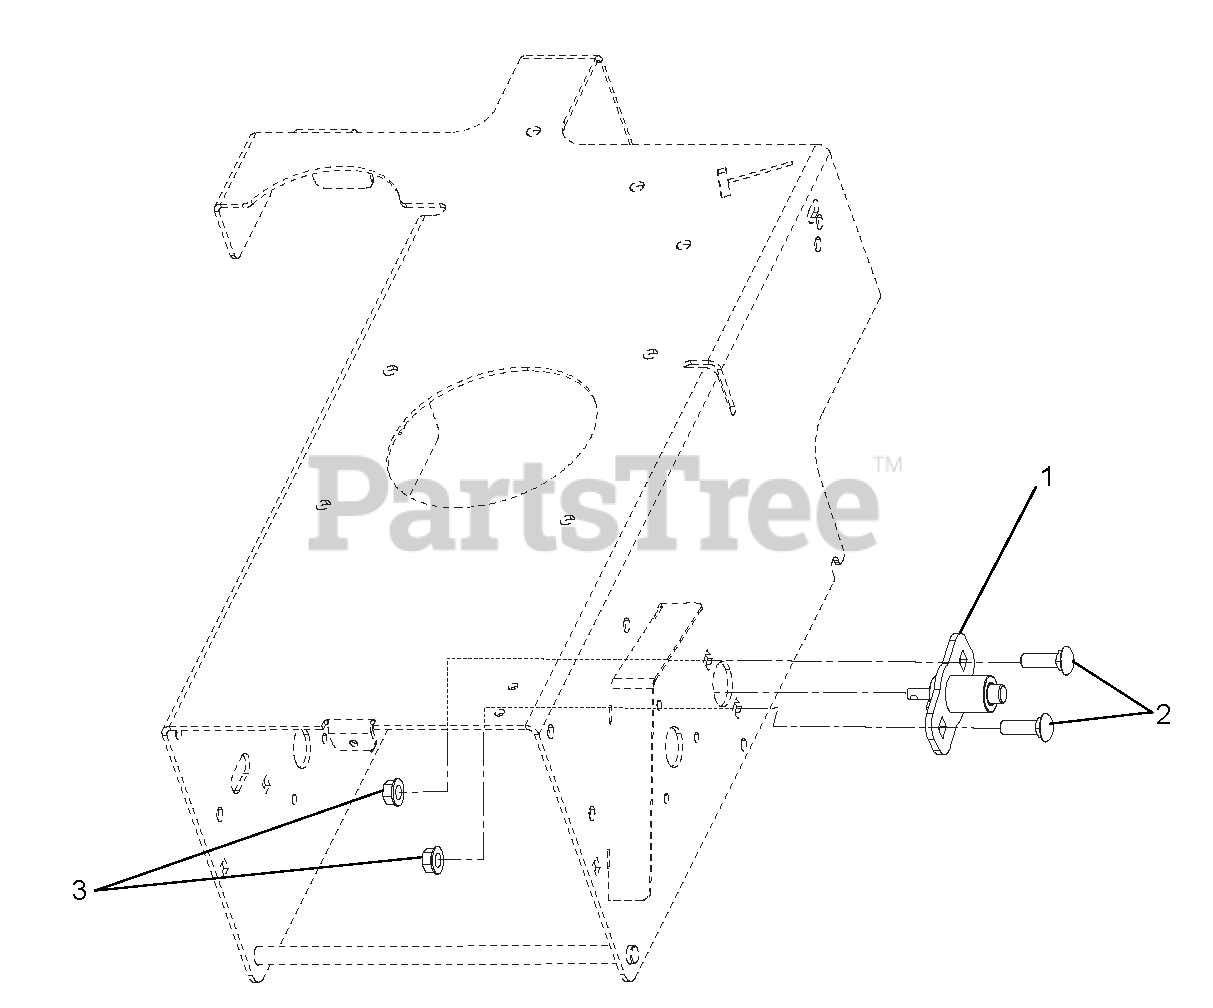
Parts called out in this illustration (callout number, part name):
1	KIT, WAW PIN BRAKE
2	@BLT-RDHDSQNK .38-16X1.25 G5YZ
3	@NUT-SPNLK-FLG .375-16 YWZC
